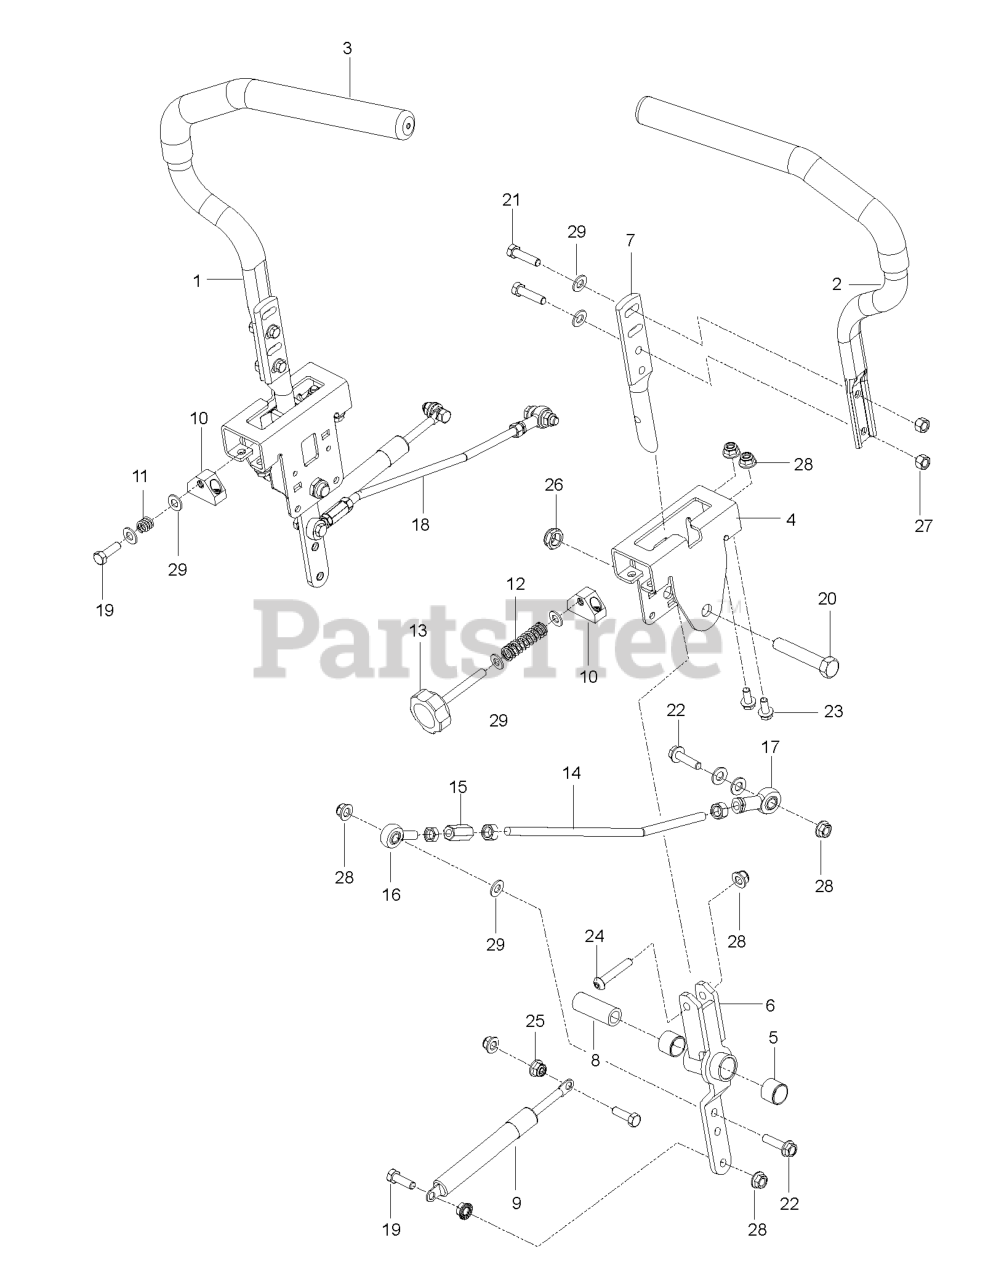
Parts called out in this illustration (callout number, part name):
1	TUBE.LEVER.CNTL.ASM.ZTR.RT.SVC
2	TUBE.LEVER.CNTL.ASM.ZTR.LT.SVC
3	PURCHASE THE COMPLETE LEVER
4	BRACKET.CONTROLS.ZTR.X431
5	BEARING.PT.750
6	CONTROL.WELDMENT.RZ
7	LEVER.HANDLE MOUNT
8	SPACER.PIVOT.CONTROL
10	BLOCK TRACKING CONTROL ZTR
12	SPRING COMPRESSION 2.0
13	KNOB
14	ROD, CONTROL
15	ROD END COUPLER
16	ROD.END.MALE.LH.THREAD
17	JOINT.HEIM.FEML.5/16.RH.THREAD
19	BOLT.5/16-18X1-1/4 FULL.THREAD
20	HCS 1/2-13 X 2-3/4 GD 5 ZD
21	CAPSCREW 5/16 X 1/1/2 HEX HEAD
22	HHFS 5/16-18 X 1.25 TPBLT GD 5
23	HHFS 5/16-18 X 3/4
24	SCREW 5/16-18 X 1 3/4 BTN-HD
25	NUT 5/16C WHIZ
26	NUT 1/2-13 HEX JM NYL
27	NUT 5/16 NYLOC
28	5/16-18 NYLOC FLANGE NUT
29	WASHER
